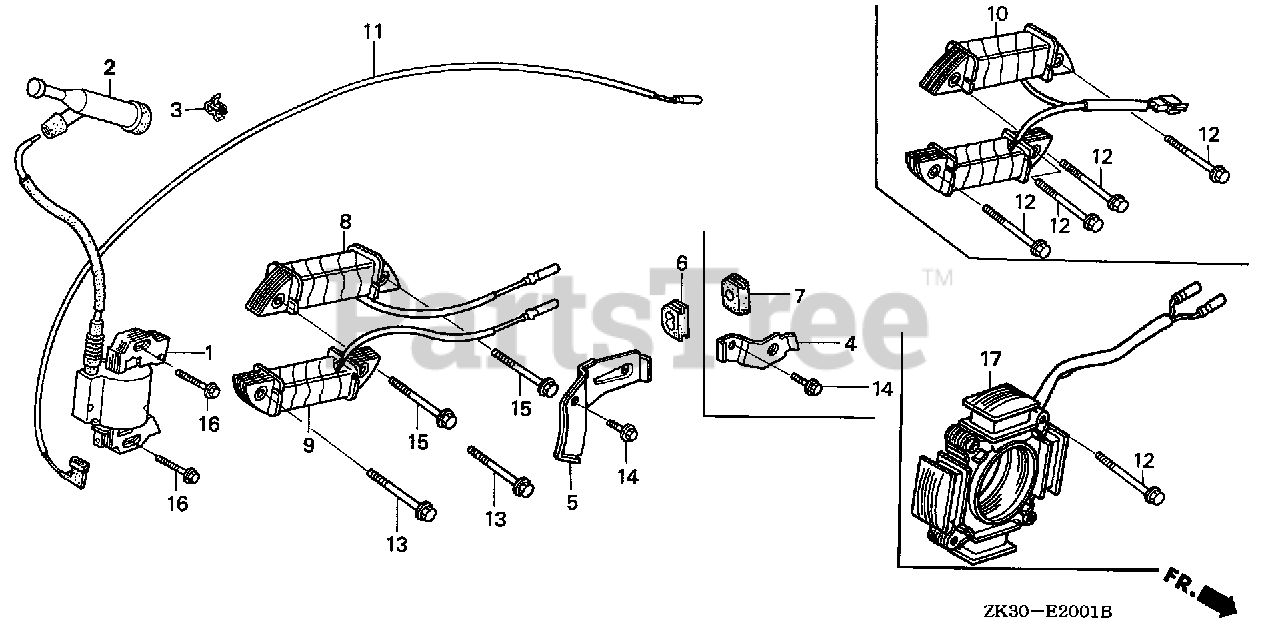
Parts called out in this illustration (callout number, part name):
1	COIL ASSY., IGNITION
2	CAP ASSY., NOISE SUPPRESSOR (NICHIWA Y-EZ RTFM256)
6	GROMMET, WIRE
11	WIRE, STOP SWITCH (430MM)
16	BOLT, FLANGE (6X28) (CT200)
